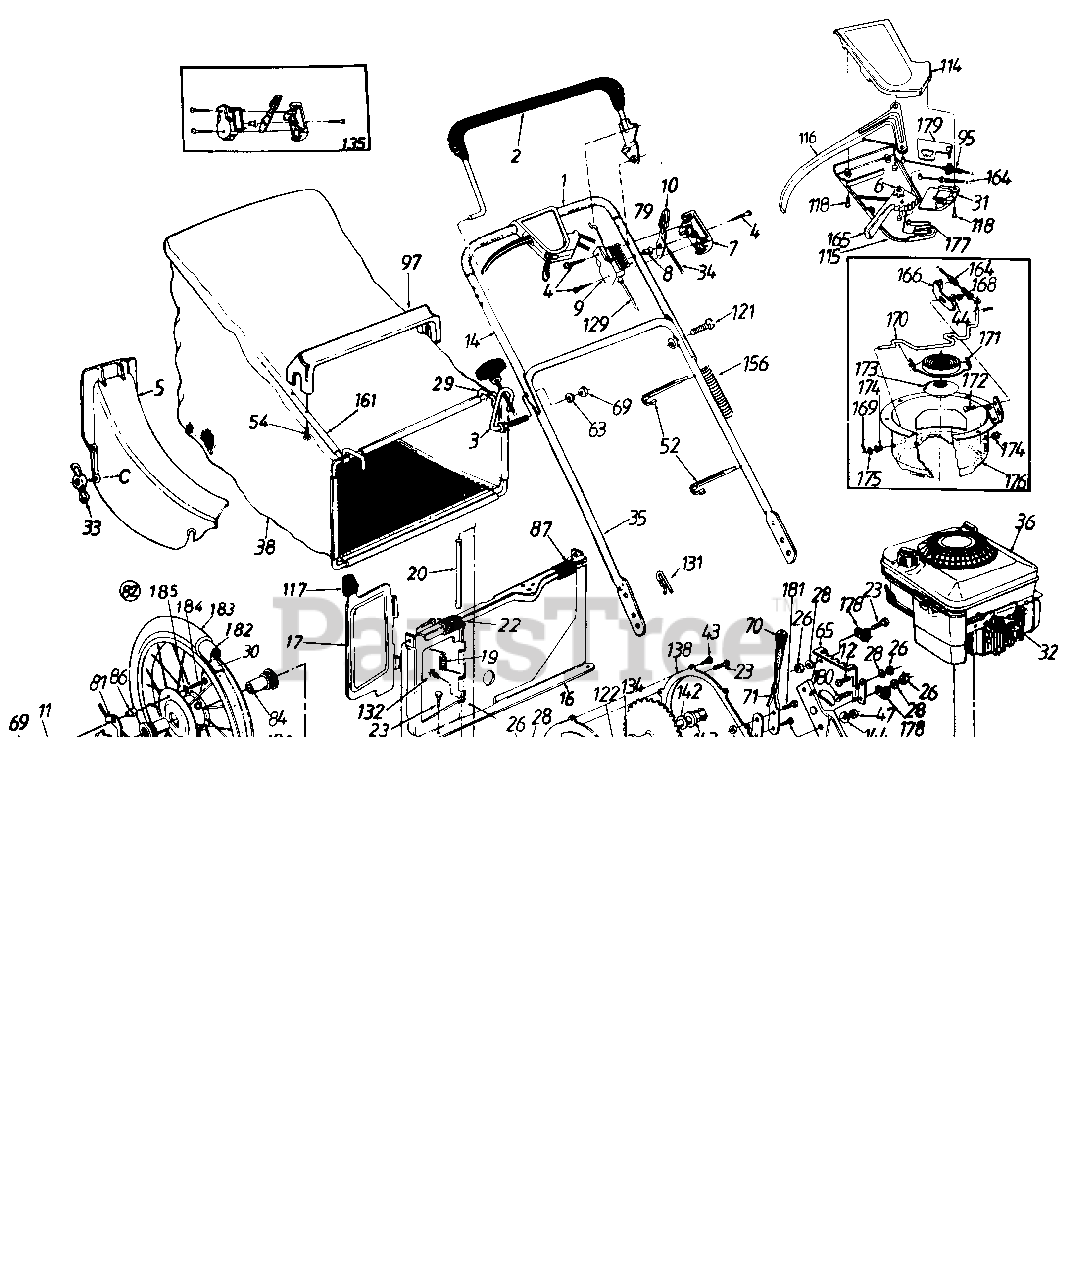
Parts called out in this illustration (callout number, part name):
1	Grip
2	Control Handle Ass'y. L.H.
3	Rope Guide Bolt
4	Truss Mach. Scr. #12 x 1.50" Lg.
5	Rear Discharge Chute Ass'y.
6	3 Tooth Rack Gear Insert
7	Control Panel Half
8	Control Disc Pin
9	Clutch Panel Half
10	Throttle Control Lever
11	Wheel Cover
12	Truss Mach. Scr. 1/4-20 x .62" Lg.
14	Upper Handle
15	Panel Support Brkt.
20	Pivot Pin
21	Carriage Bolt 1/4-20 x .62"
22	Truss Mach. Scr. 1/4-20 x .75" Lg.
23	Hex Bolt 1/4-20 x .5" Lg.
24	Shoulder Bolt Special
25	Hex Bolt 1/4-20 x .62" Lg.
26	Hex Nut 1/4-20 Thd.
27	Wheel Ratchet
28	L-Wash. 1/4" I.D.
30	Rim Strip
31	S.P. Control Cover
32	Spark Plug Insulator
33	Wing Nut
34	Throttle Control Wire 61"
35	Lower Handle
36	Engine
38	Grass Bag
39	Retaining Strip
41	Fl-Wash. .344" I.D. x .62"
42	Rear Support Drive Ass'y.
43	Hex B-Tap Scr. 1/4" x .38"
44	Bell-Wash. 1/4" I.D.
45	Hex AB-Tap Scr. 1/4 x .62"
47	Hex Patch L-Nut 3/8-24 Thd.
48	#48 Chain .500" Pitch x 52 Links
51	Rear Flap
52	Cable Tie (w/Post)
54	Hex AB-Tap Scr. #12 x 1.25" Lg.
55	Blade Adapter Kit
56	21" Blade
58	Bell-Wash. .46" I.D.
60	Hex Bolt 7/16-20 x 1.5"
61	Spacer .628" I.D.
63	L-Wash. 5/16" I.D.
64	Handle Brkt. Ass'y. R.H.
65	Handle Brkt. Ass'y. L.H.
66	Carriage Bolt 5/16-18 x .62"
67	Hex B-Tap Scr. 5/16-18
68	Hex TT-Tap Scr. 3/8-16
69	Hex Nut 5/16-18 Thd.
71	Height Adj. Lever
72	Flanged L-Nut 3/8-16 Thd.
73	Bell-Wash. 5/16" I.D.
74	Spacer .383" I.D.
76	Rope Guide
77	Bolt Retainer 1/4 x .50" O.D.
79	Control Label
80	Hex Bolt 1/4-20 x .75" Lg. (Grade 5)
81	Pawl and Spring Ass'y.
82	Wheel Ass'y. Comp.
84	Flange Bearing 63" I.D.
86	Special Hex Nut 5/16-18 Thd.
87	Panel Clip
95	S.P. Cable 50" Lg.
96	"V"-Belt
97	Bag Handle
98	Spacer 63" I.D. x 1.25"
99	Hex Bolt 3/8-24 x 1.0" Lg.
100	Hex Nut 3/8-24 Thd.
101	L-Wash. 3/8" I.D.
115	Self-Propelled Control Cover
116	Control Lever
117	Door Grip
118	Fl-"C"-Sunk Hd. Tap Scr. #10 x .75" Lg.
121	Curved Carr. Bolt 5/16-18 x 1.38" Lg.
122	Sprocket and Axle Ass'y.
129	Control Cable 39"
131	Intern. Cotter Pin 1/8" Dia.
132	Hex B-Tap Scr. #10 x .38" Lg.
133	Side Chute Deflector Ass'y.
134	Hex Flange Bearing
135	Kit Control Housing Comp.
138	Chaincase and Arm Ass'y.
140	Hex S-Tap Scr. 1/4-20 x .50"
141	Fl-Wash. .632" I.D. x .943"
142	Fl-Wash. .635" I.D. x 1.0"
143	Hex Flange Brg. .631" I.D.
144	Fl-Wash. .385" I.D. x .87"
153	Transmission Comp.
156	Plastic Tubing
164	Spd. Control Cable 50" Lg.
165	6-Spd. Shift Lever
169	Cot-Pin 3/32" Dia. x .75" Lg.
170	Shift Rod
171	Movable Pulley Half Ass'y.
172	Carr. Bolt 1/4-20 x .5" Lg.
173	Splined Pulley Half
174	Flanged Bushing
175	Fl-Wash. .328" I.D. x .68" O.D.
176	Cable Mtg. Brkt. Ass'y.
177	Shift Lever Spring
178	Clamp
179	6-Spd. Rack Cable Brkt.
180	Truss Mach. Scr. 1/4-20 x .75" Lg.
181	Hex Bolt 3/8-16 x .62" Lg.
182	Inner Tube 16" x 2.12"
183	Chevron Tire 16" x 2.125"
184	Hex Bolt Special 5/16-18 x 1" Lg.
185	Intern Lock Wash. 5/16" I.D.
186	Rim Ass'y. Only 16" x 2.1"
